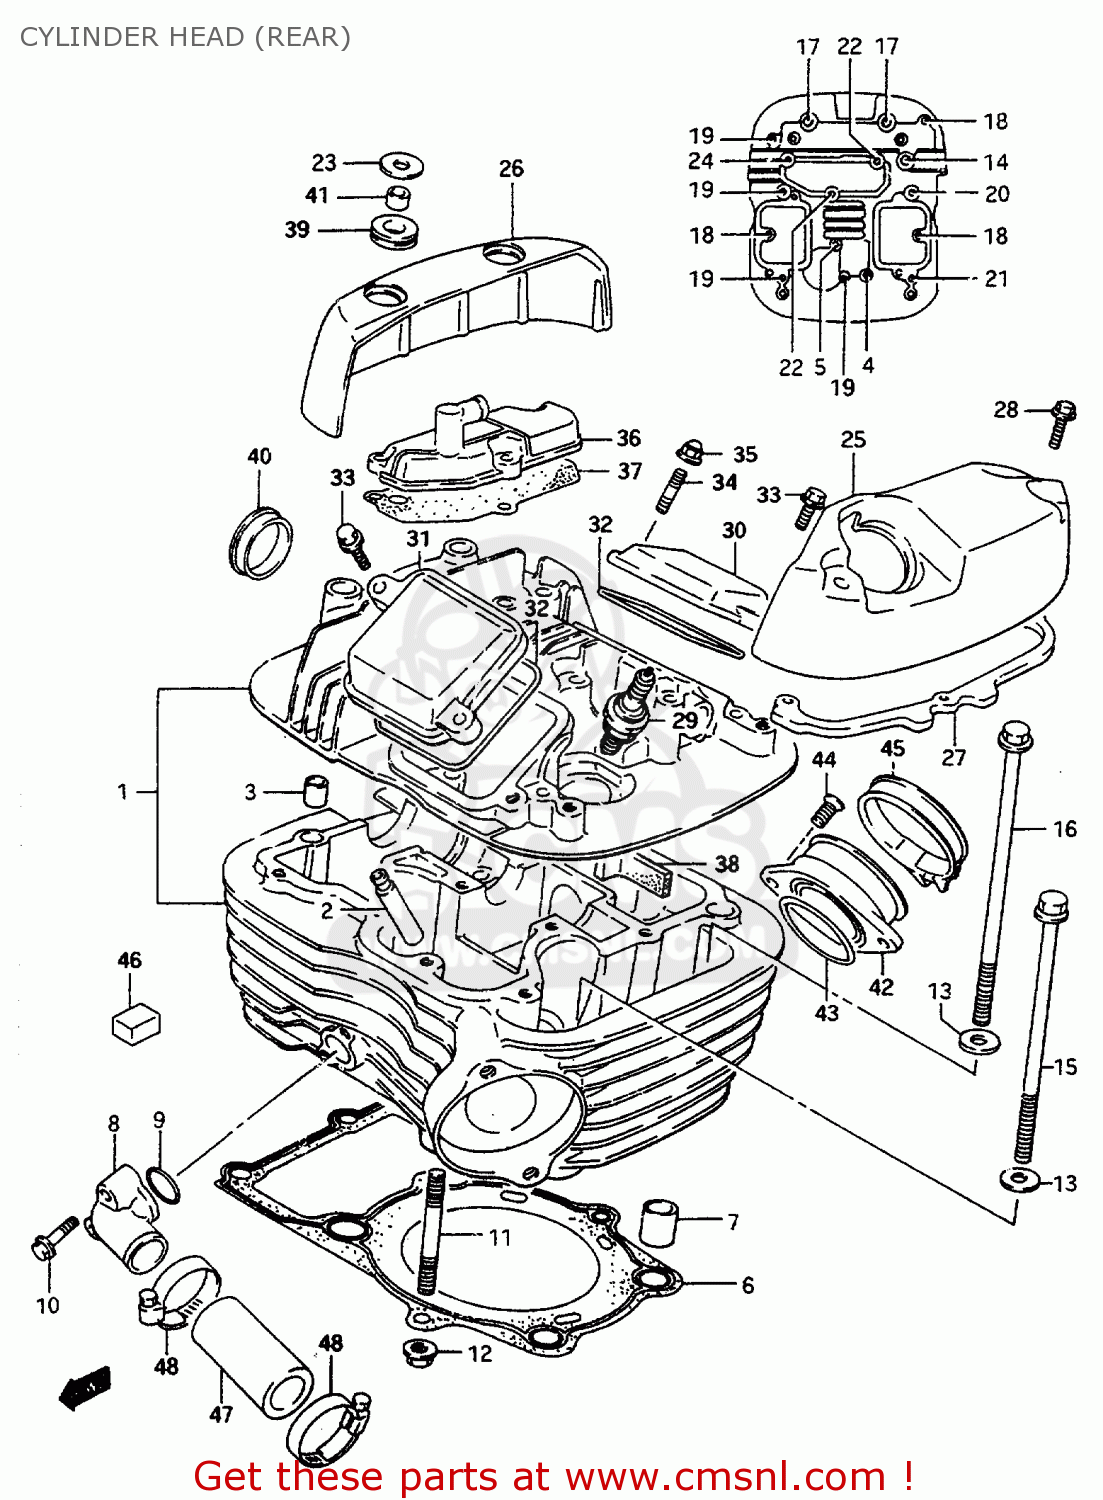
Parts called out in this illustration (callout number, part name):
1	HEAD ASSY,CYLINDER RR
2	GUIDE,VALVE
3	PIN(8.4X11X14)
4	BOLT(6X50)
5	BOLT(6X55)
6	GASKET,CYLINDER HEAD RR (MCA)
7	PIN
8	UNION,CYLINDER HEAD WATER
9	O RING(D:2.4,ID:17.8)
10	BOLT
11	BOLT,STUD
12	NUT
13	WASHER (10.5X22X2.3)
14	BOLT(8X140)
15	BOLT(10X155)
16	BOLT(10X165)
17	BOLT(8X245)
18	BOLT
19	BOLT
20	BOLT
21	BOLT
22	BOLT(6X55)
23	WASHER (8.2X24X1.6)
24	BOLT
25	CAP,CYLINDER HEAD COVER RR,L
26	CAP,CYLINDER HEAD COVER RR,R
27	CUSHION,RR,L CAP
28	BOLT
29	PLUG,SPARK(DPR8EA-9)
30	CAP,INSP.INT
31	CAP,INSPECTION,EXHAUST
32	GASKET,INSPECTION CAP (NAS)
33	BOLT
34	STUD 6X16
35	NUT
36	COVER,BREATHER
37	GASKET,BREATHER COVER (NAS)
38	PLATE,HEAD COVER RR
39	CUSHION
40	PLUG(OD:30)
41	BUSH
42	PIPE,INTAKE RR
43	O-RING (D:2.4 ID:39.7)
44	SCREW
45	CLAMP
46	PAD
47	HOSE,CYLINDER HEAD JOINT
48	CLAMP
